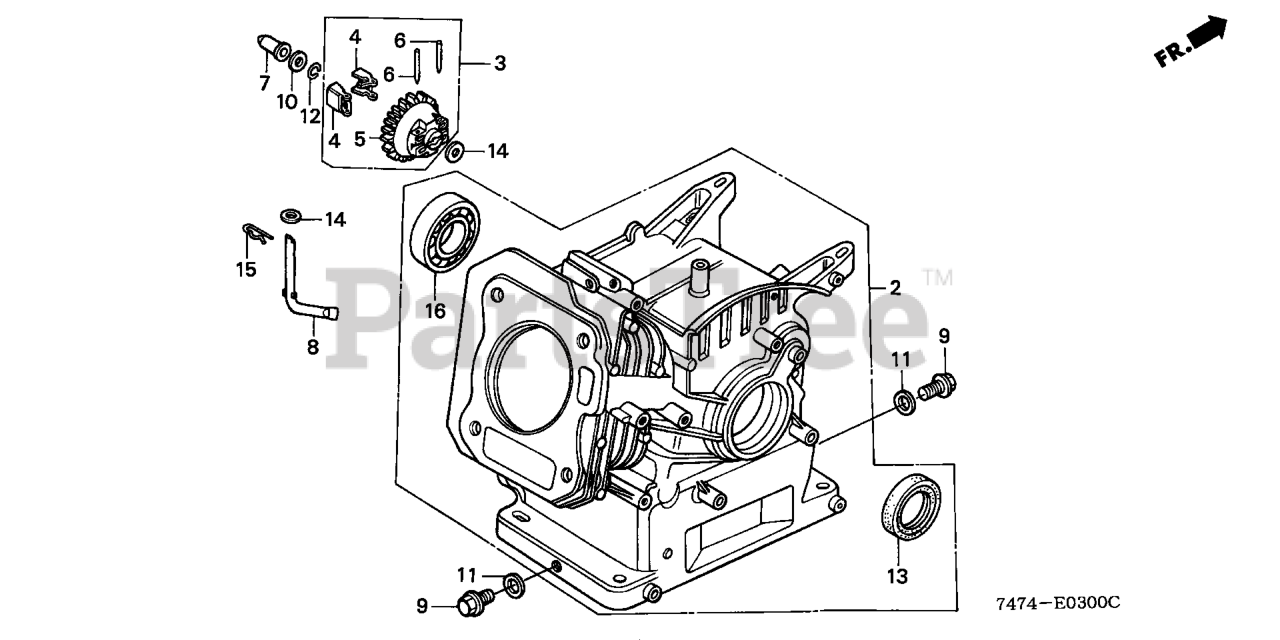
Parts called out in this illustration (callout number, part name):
2	CYLINDER ASSY.
3	GOVERNOR ASSY.
4	WEIGHT, GOVERNOR
5	HOLDER, GOVERNOR WEIGHT
6	PIN, GOVERNOR WEIGHT
7	SLIDER, GOVERNOR
8	SHAFT, GOVERNOR ARM
9	BOLT, DRAIN PLUG
10	WASHER, THRUST (6MM)
11	WASHER, DRAIN PLUG (10.2MM)
12	CLIP, GOVERNOR HOLDER
13	OIL SEAL (25X41X6)
14	WASHER, PLAIN (6MM)
15	PIN, LOCK (8MM)
16	BEARING, RADIAL BALL (6205)
